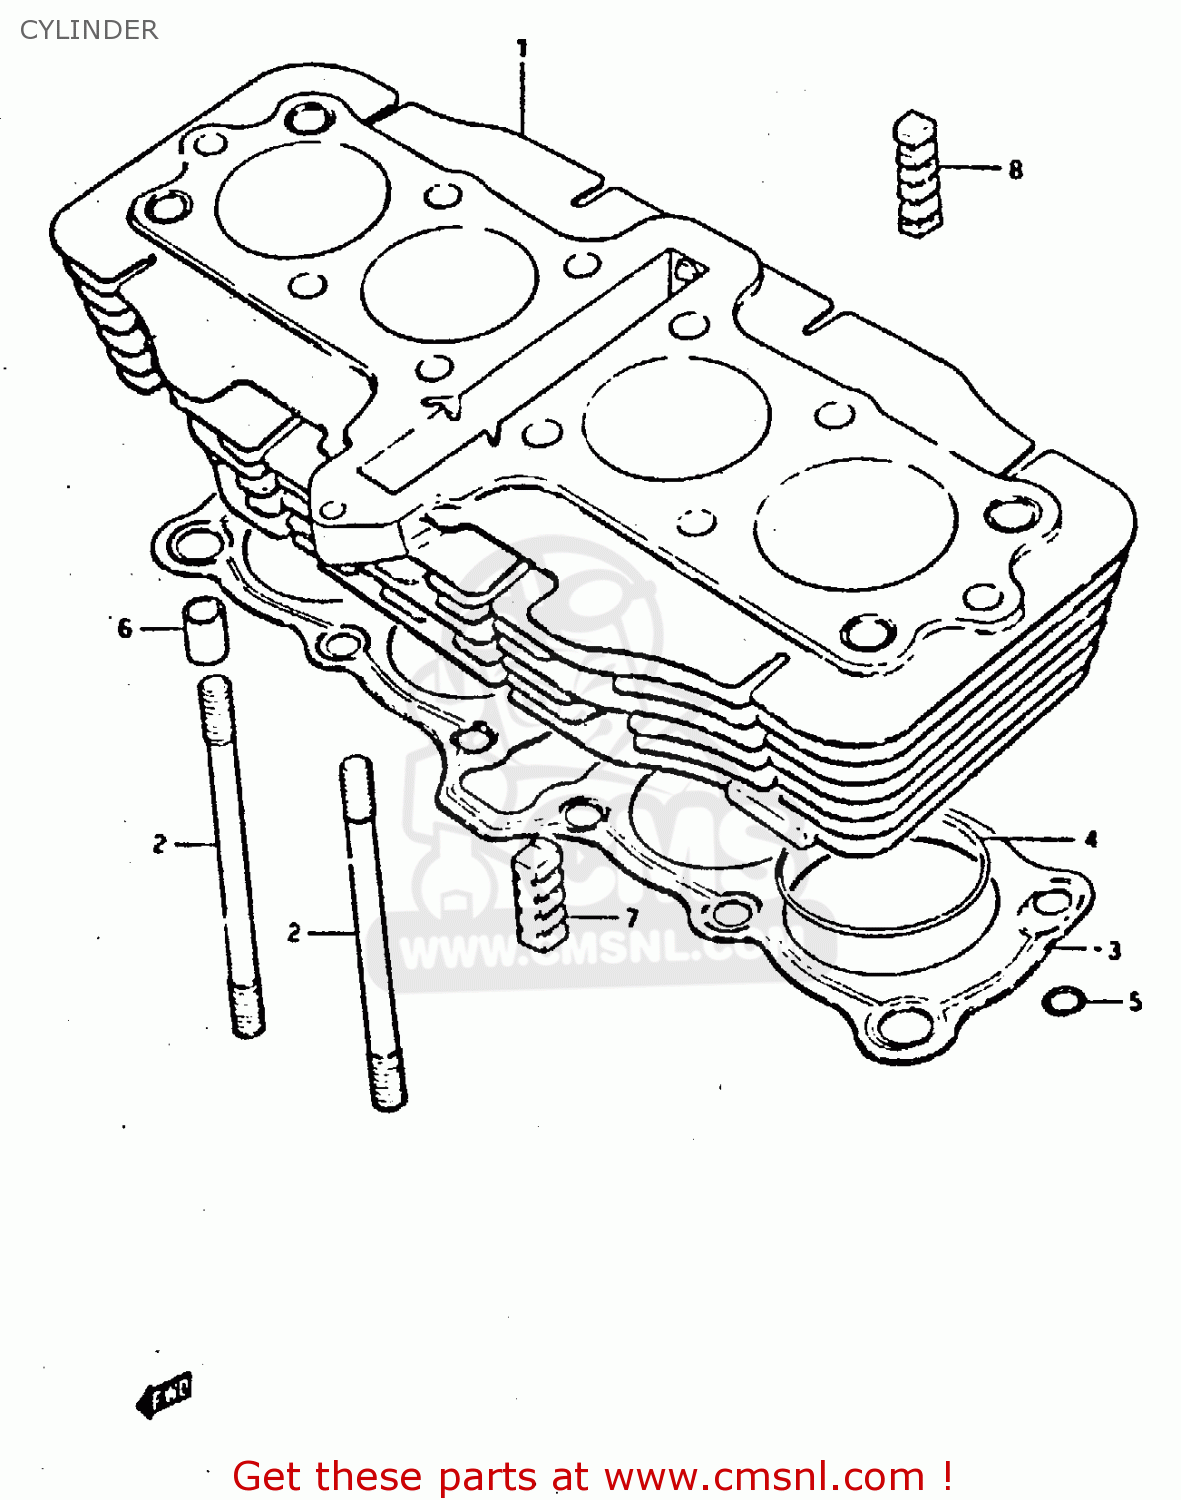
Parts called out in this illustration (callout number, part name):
1	CYLINDER
2	STUD
3	GASKET,CYLINDER
4	O RING(D:2,ID:61)
5	O RING(D:2.4,ID:12.3)
6	PIN
7	PAD,CYLINDER
8	PIN,EXHAUST VALVE
